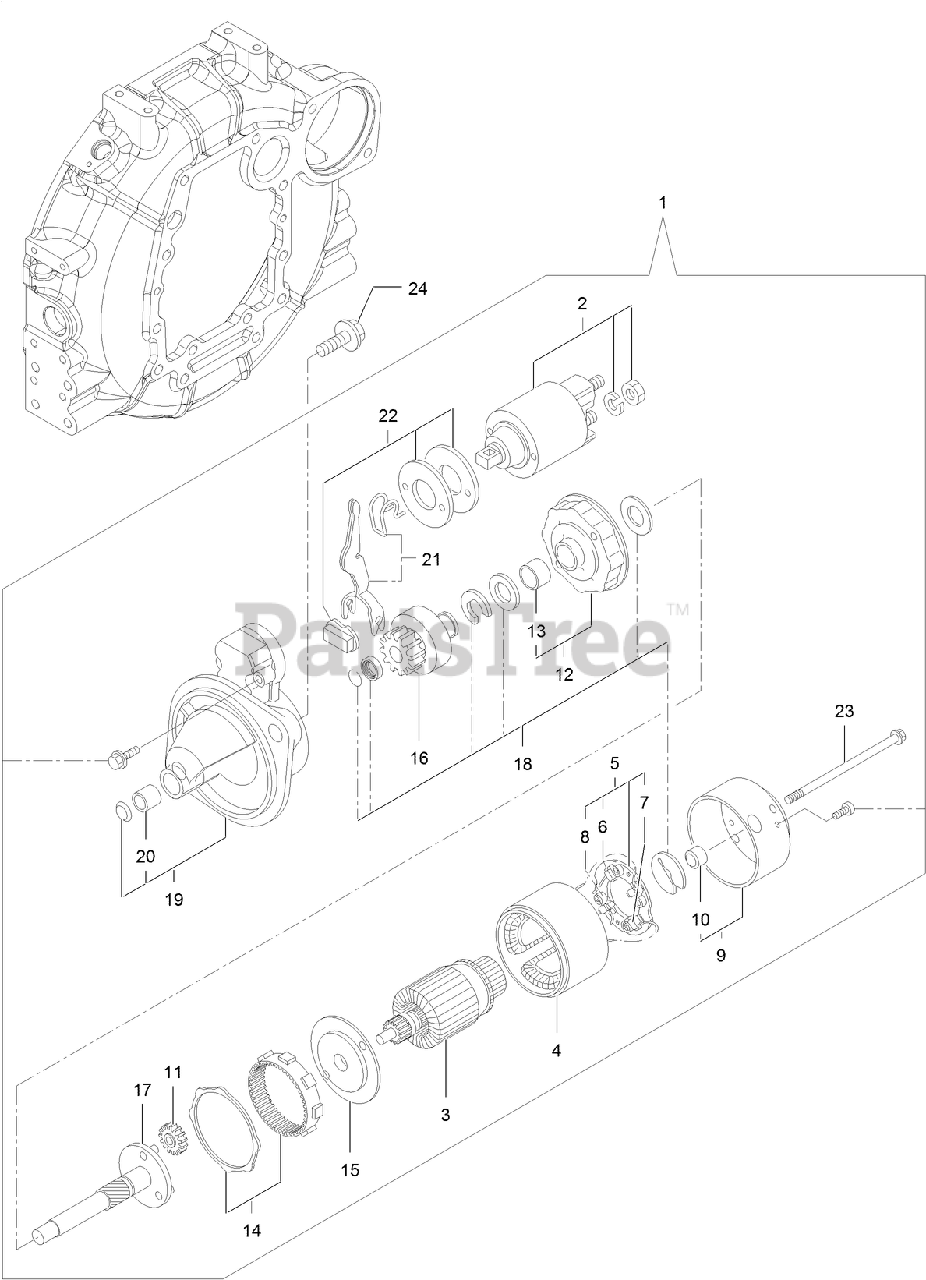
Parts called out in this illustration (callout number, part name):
1	STARTER ASM
2	SWITCH ASM
3	ARMATURE ASM
4	YOKE ASM
5	BRUSH HOLDER ASM
7	BRUSH SET
8	SPRING
9	COVER ASM
12	BRACKET
13	BRACKET
15	BRACKET
16	PINION ASM
18	WASHER SET
19	CASE ASM
20	METAL-STARTER
21	LEVER SET
22	DUST COVER ASM
23	BOLT-THROUGH
